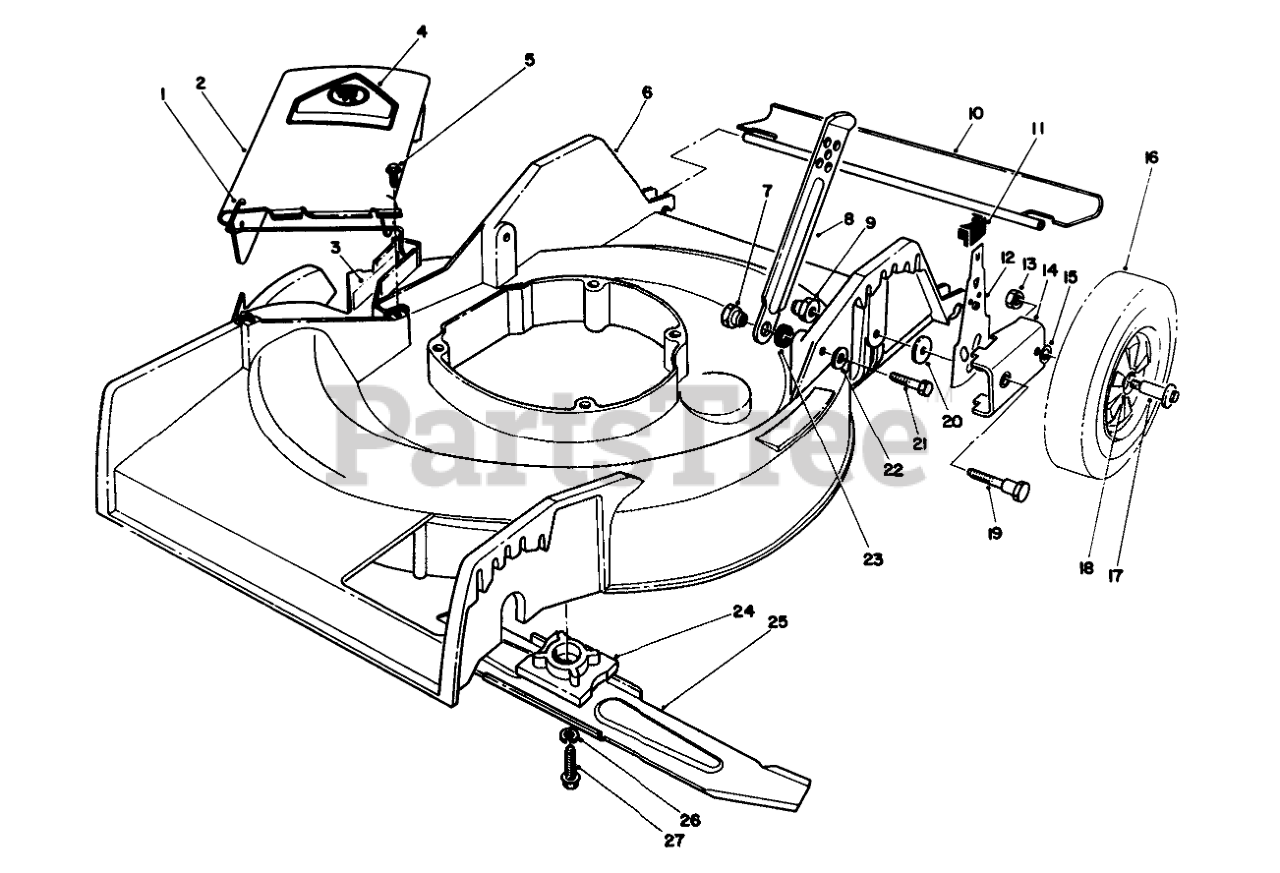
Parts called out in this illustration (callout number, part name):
1	SPRING HINGE
2	Deflector (Incl. Ref. #1 & 3)
3	DANGER DECAL
4	DECAL-DANGER
5	SCREW-HWH
6	HOUSING W/DECAL
7	HANDLE PIVOT NUT
8	HANDLE LATCH
9	HANDLE PIVOT NUT
10	SHIELD - TRAILING
11	KNOB-ARM
12	SPRING ARM ASSEMBLY
13	Nut
14	HP PIVOT ARM ASM
15	WASHER
16	Wheel & Tire Assembly (Incl. Ref. #18)
17	BOLT-WHEEL
18	BUSHING
19	PIVOT SCREW
20	PIVOT WASHER
21	SCREW-HH
22	WASHER-LOCK
23	SPACER
24	BLADE RETAINER
25	Blade
26	WASHER-LOCK
27	SCREW-HH
